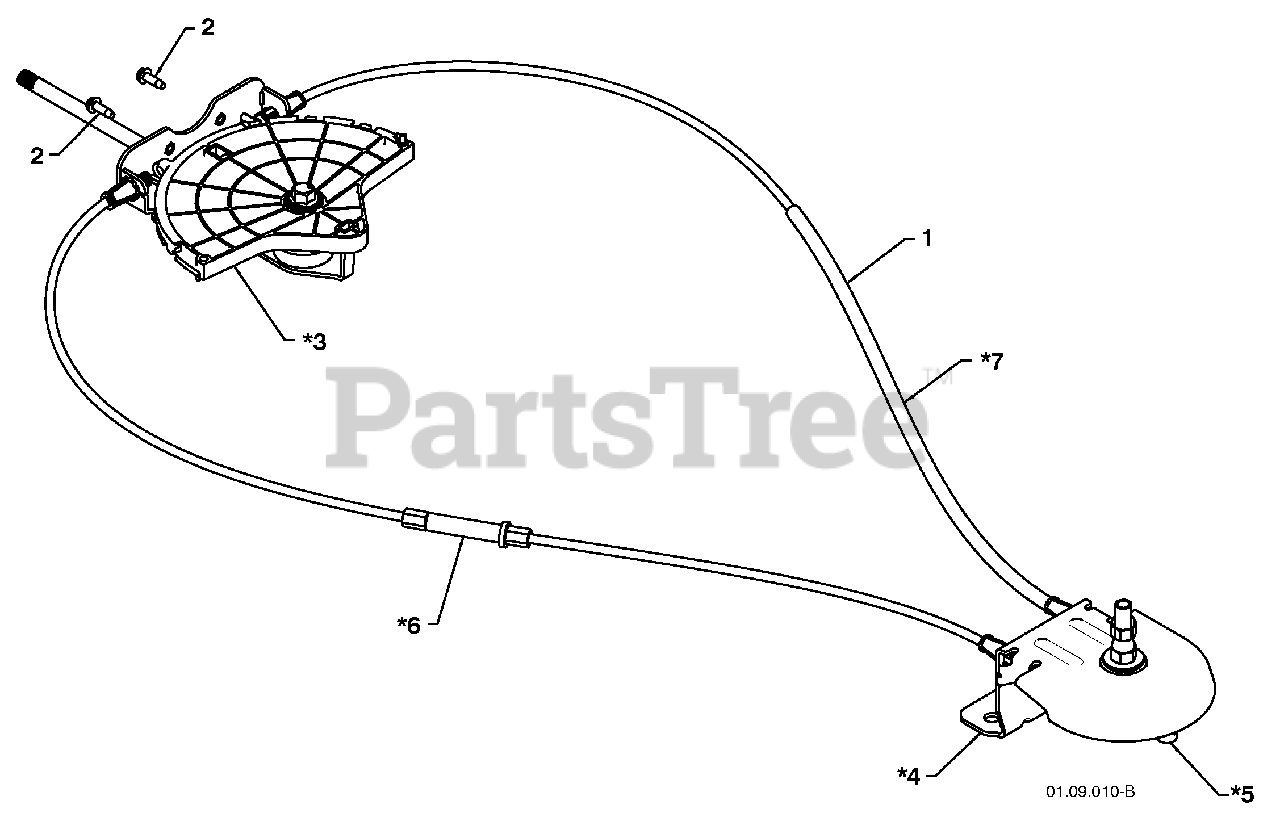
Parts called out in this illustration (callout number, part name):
1	LEVER/CABLE ROTATOR ASSEMBLY
2	SCREW 10-24 X .625
3	ROTATOR HEAD
4	ROTATOR PIVOT BRACKET
5	PULLEY PIVOT
6	CABLE ASSEMBLY ADJUSTABLE
7	CABLE ASSEMBLY HEAT SHIELD
